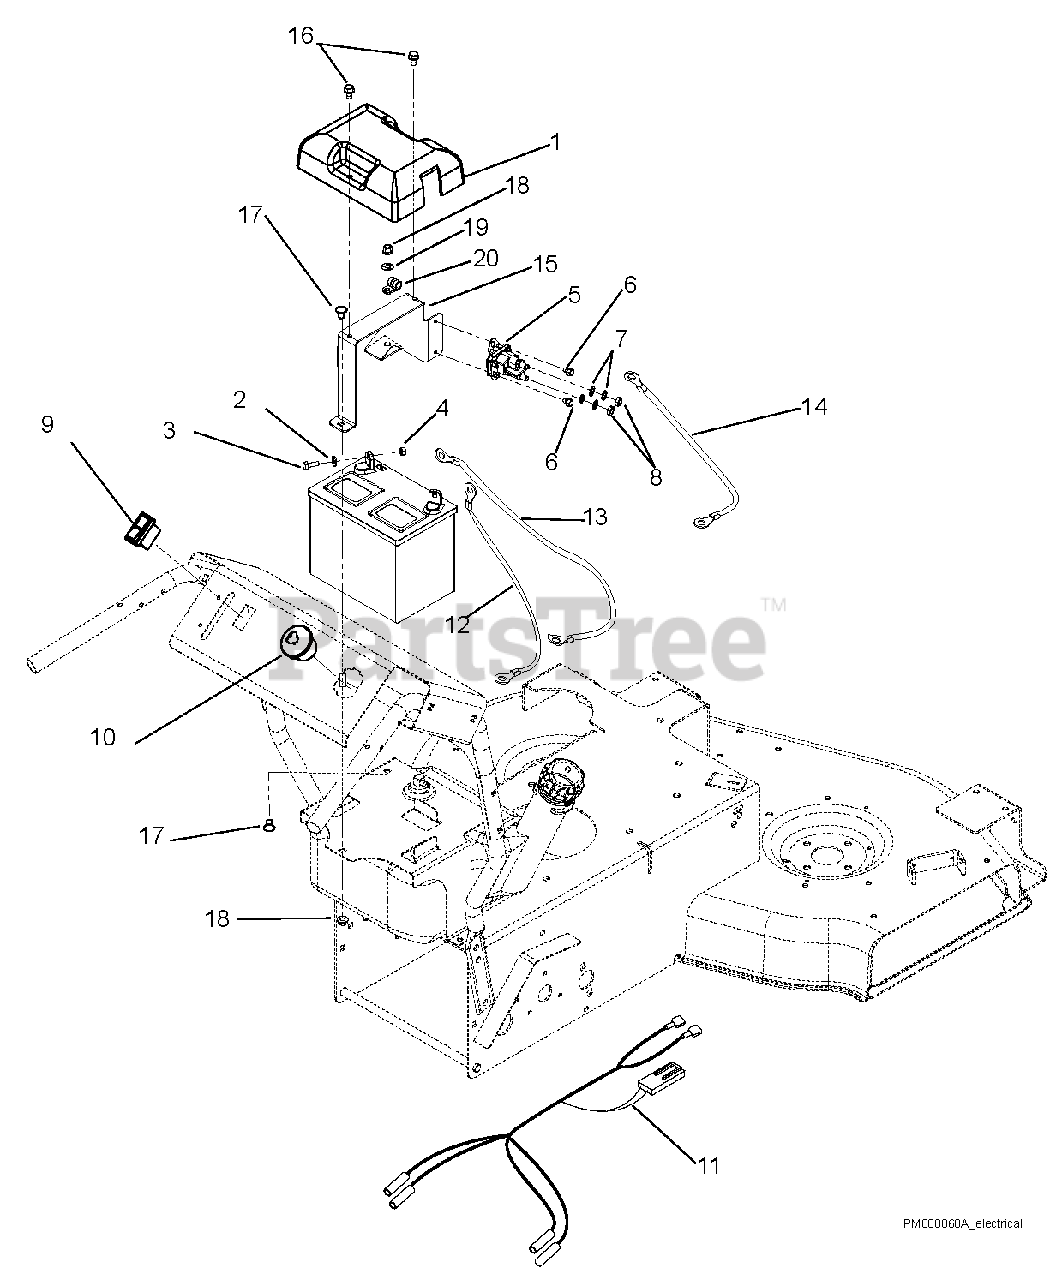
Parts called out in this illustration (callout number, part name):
1	Cover, Battery
2	Washer, Flast Steel .281 x .62 x .065
3	Bolt, Hex .25-20 x .75
4	Nut, KEPS .250-20
5	Solenoid
6	Screw, Tapping Hex Washer Head .250-20 x .37
7	Washer, Internal Lock .31
8	Nut, Jam .31-24
9	Switch, Rocker
10	KEYSWITCH-IGNITION 3 POS
11	Harness, Wiring
12	Cable, Positive Battery 18.50"
13	Cable, Ground 22.0"
14	Cable 6.75"
15	Bracket, Battery Mount
16	Screw, Tapping .31-18 x .50 Hex Washer Head
17	Bolt, Round Head Square Neck .31-18 x .50
18	Nut, Locking-Top-Flange .31-18
19	Nut, Push .312
20	Clamp, Cushioned Steel (Serials 2500 and up)
NS	Replacement Key
